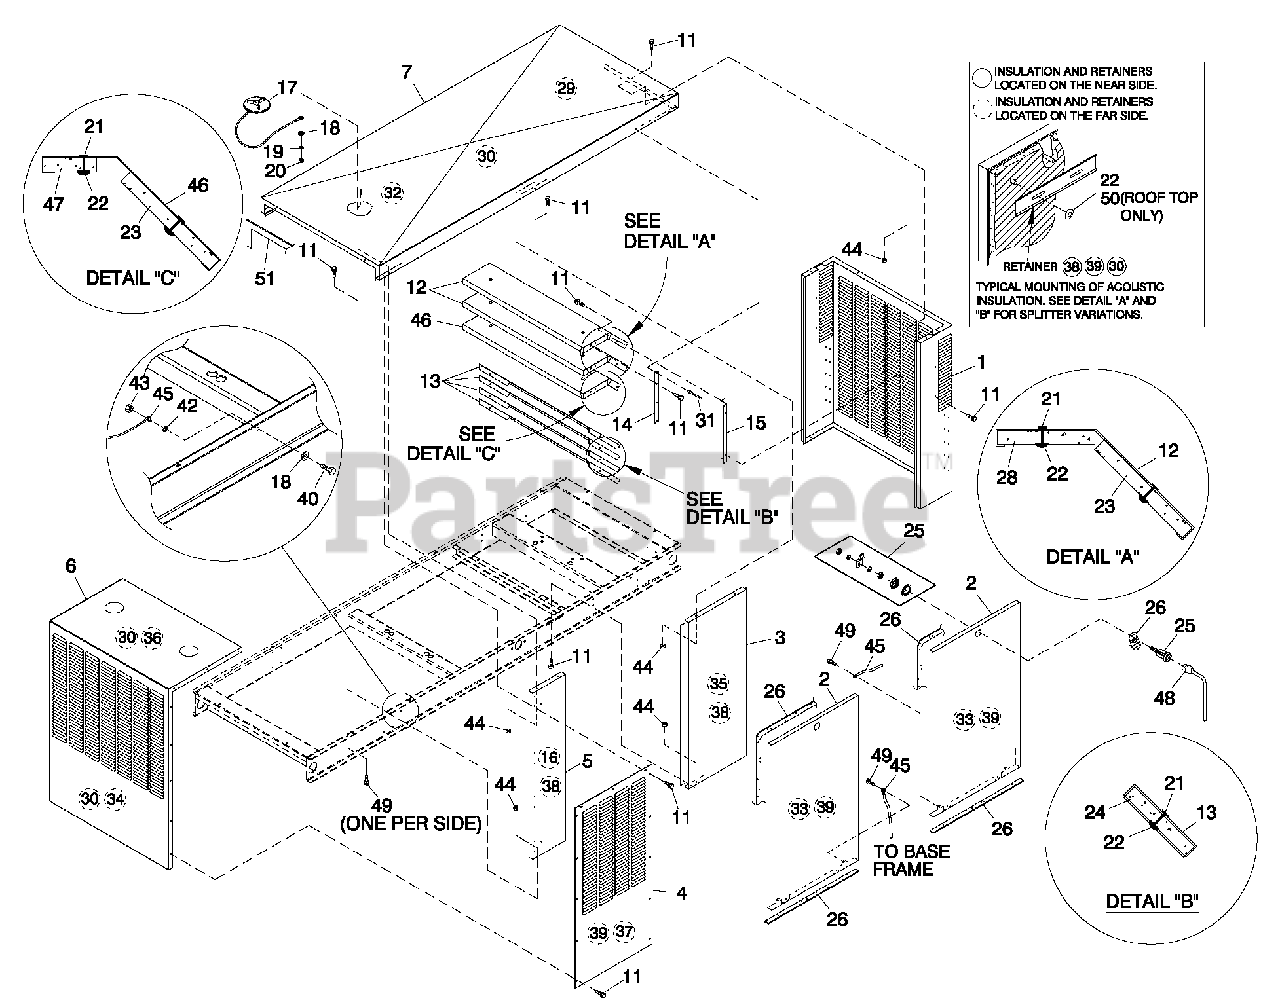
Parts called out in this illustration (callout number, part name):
1	REAR WRAP C5
2	DOOR C5
3	CENTER SUPPORT C5
4	DISCHARGE DUCT LH & RH SIDE C5
5	FRONT CORNERS C5
6	DUCT CENTER DISCHARGE (CATALYST EQUIPPED UNITS)
7	ROOF C5ALUM
11	SCREW THF M6-1 X 16 N WA Z/JS
12	SPLITTER
13	SPLITTER SHORT
14	STRINGER SPLITTER C3
15	SUPPORT SPLITTER C5 130KW
16	INSULATION CORNER POST
17	ASSY ACCESS COVER
18	WASHER FLAT 1/4-M6 ZINC
19	WASHER LOCK M6-1/4
20	NUT HEX 1/4-20 STEEL
21	INSULATION RETAINMENT HANGER
22	WASHER SELF LOCKING DOME #4-40
23	INSULATION SPLITTER
24	INSULATION SHORT LOUVER
25	VISE-ACTION LATCH SLOTTED CIR
26	GASKET EXTRUDED TRIM (566" LG)
27	TAB PULL
28	INSULATION SPLITTER SML
29	INSULATION ROOFTOP REAR
30	RETAINER INSULATION (740)
31	RIVET POP .1875 X .450 SS
32	INSULATION ROOFTOP
33	INSULATION DOOR
34	INSULATION DISCHARGE DUCT
35	INSULATION CENTER SUPPORT
36	INSULATION DISCHARGE DUCT TOP
37	INSULATION INNER DUCT SIDE
38	RETAINER INSULATION (820)
39	RETAINER INSULATION (450)
40	SCREW HHC M6-1.0X 20 G8.8
42	WASHER SHAKEPROOF INT 1/4
43	NUT HEX M6X 1.0 G8YEL CHR
44	NUT HEX LOCK M6-1.0 SS NY INS
45	ASSY WIRE 14 AWG 34.8" GRN/YEL
46	SPLITTER C5
47	INSULATION SPLITTER SHRTMPS
48	KEY VISE-ACTION LATCH SLOT CIR
49	SCREW TH-FRM M6 W/CAP SHKPRF W
50	WASHER SELF LOCKING DOME #8-32
51	STRIP SEALANT 1/8 X 1 (44.52" LG)
